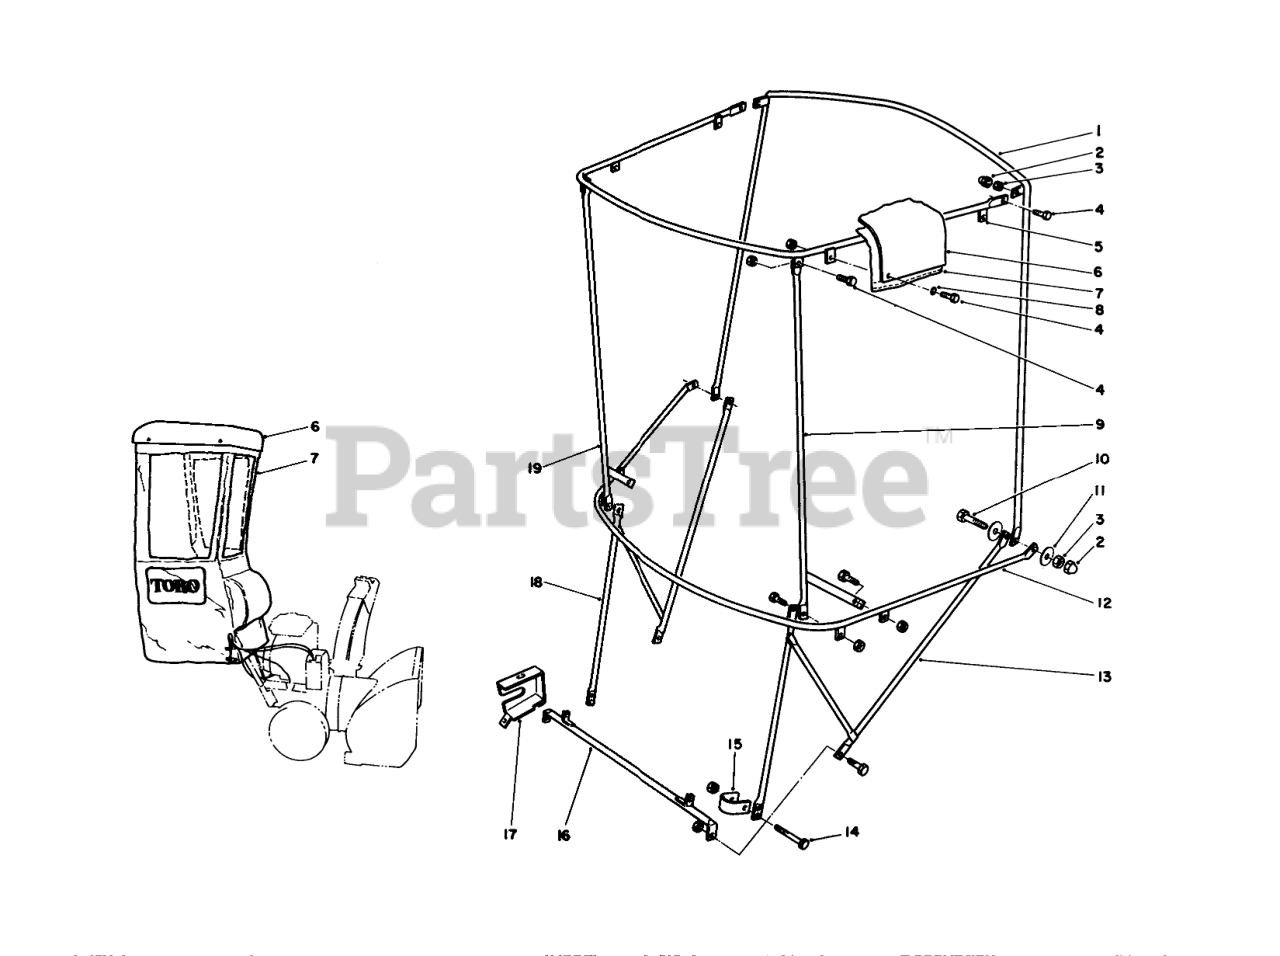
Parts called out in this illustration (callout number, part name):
1	VERTICAL BOW
2	CAPLUG
3	NUT-HEX, SIDE DEFORM
4	SCREW-HH
5	FRAME - TOP
6	Top-Plastic
7	Cover-Vinyl
8	WASHER-FLAT
9	CORNER POST - LH
10	SCREW-HH
11	WASHER-FLAT
12	HORIZONTAL BOW
13	Bracket-LH
14	SCREW-HH
15	CLAMP
16	Bracket-Base
17	COVER-LOCK, LEVER
18	BRACKET-RH
19	CORNER POST - RH
